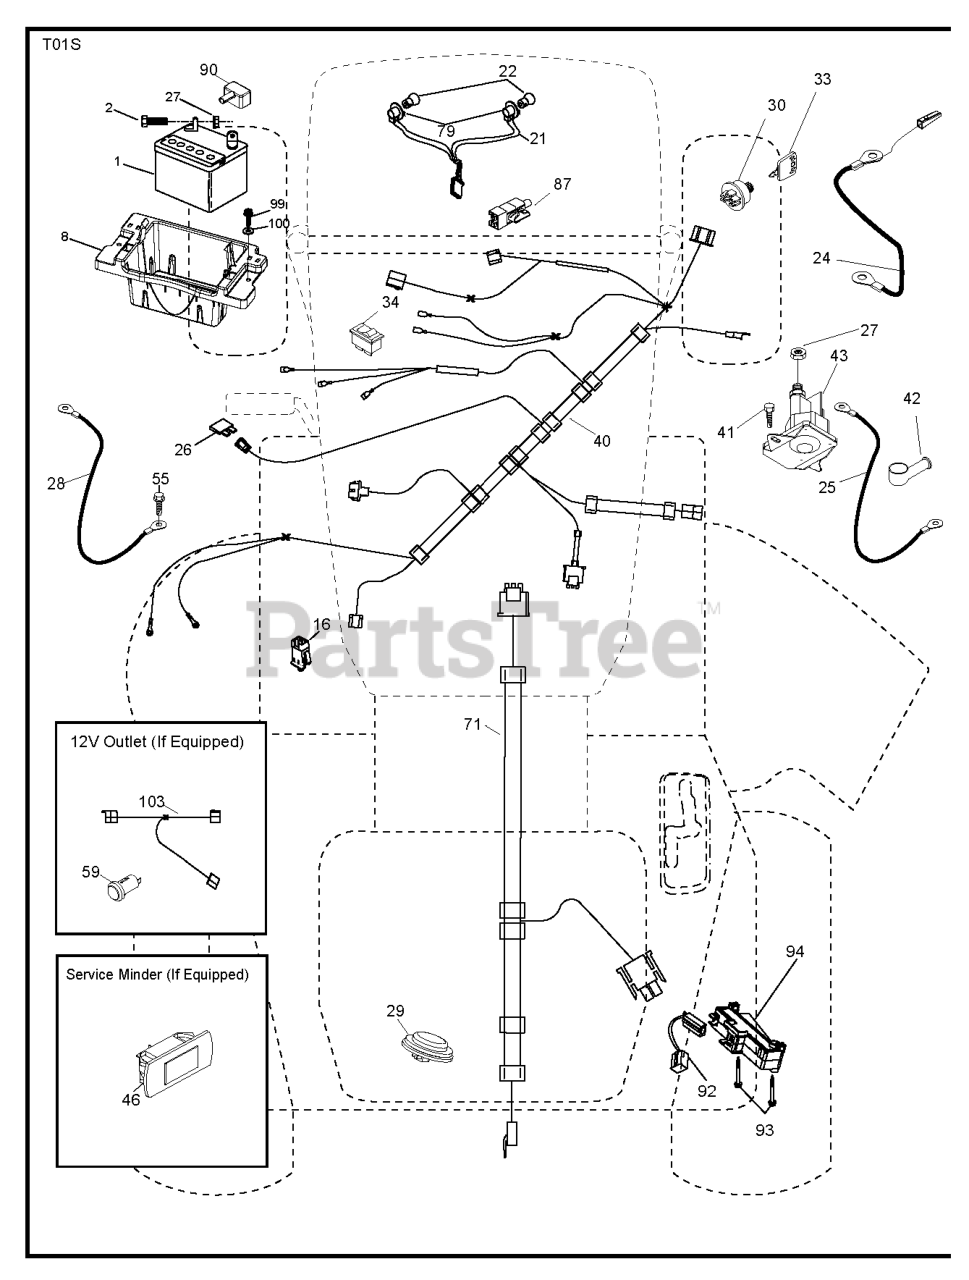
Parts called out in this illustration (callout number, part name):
1	Battery 12 Volt 25 Amp
2	BOLT.HEX.1/4.X.3/4.DICHROMATE
8	TRAY.ASM.BATTERY.FRT.TEX.CARB
16	SWITCH INTERLOOK PUSH-IN
21	HARNESS.LIGHT W/4152J BULBS
24	CABLE.FRBATT.W/WIRE.8GA.8
25	CABLE.STARTER.8GA.17.5
26	FUSE 20AMP
28	CABLE.GROUND.21"BLK.8GA.90T
29	SWITCH.SEAT.DELTA.OPC.
30	SWITCH.IGN.DELTA.W.LGH.ROS
33	KEY.CHAIN.BLISTER.PACK.GEN.USA
40	HARNESS.IGN.DASH.CBL.YTGT.PRED
41	SCREW
42	TERMINAL COVER
55	SCREW 5/16"
71	HARNESS-CHASSIS SUB
79	BULB HOLDER ASM.
87	SWITCH.INTRLCK.CLUTCH.
90	COVER.TERMINAL.BATTERY
92	HARNESS.PIGTAIL.CONSLE
94	MODULE.REVERSE.ROS
99	SCREW HEXWSHR 1/4-20X3/4
